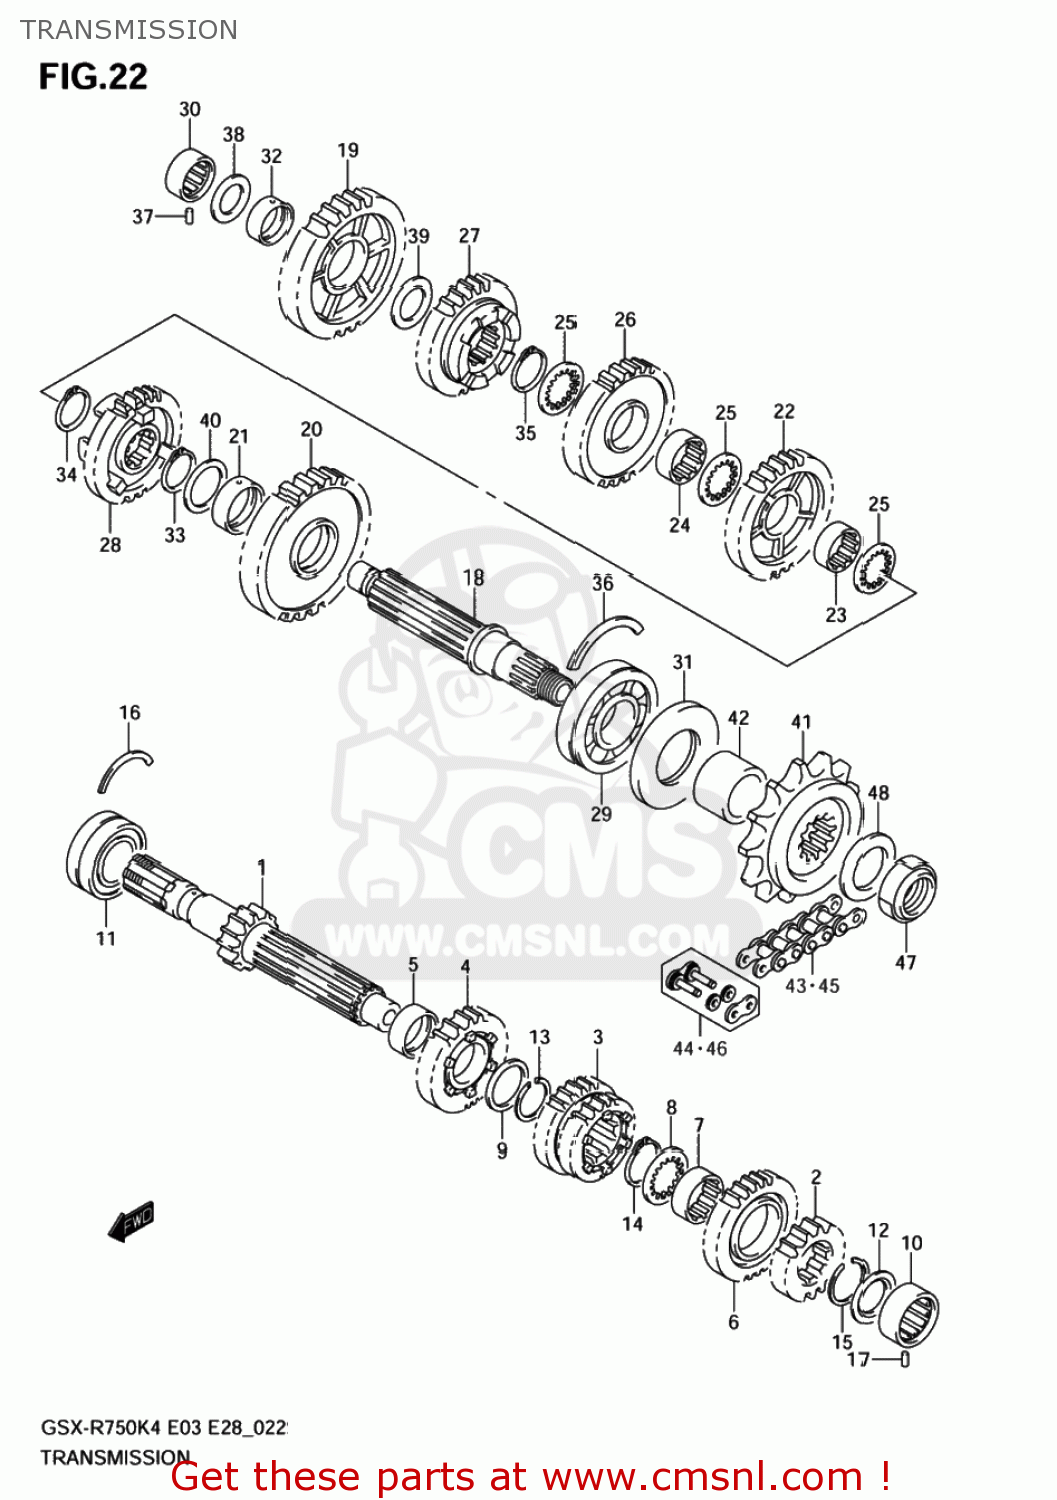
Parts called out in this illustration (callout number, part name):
1	SHAFT,COUNTER
2	GEAR,2ND DRIVE
3	GEAR,THIRD & FOURTH DRIVE
4	GEAR,5TH DRIVE
5	BUSH,5TH DRIVE GEAR
6	GEAR,6TH DRIVE
7	BUSH,6TH DRIVE GEAR
8	WASHER,LOCK
9	SHIM(27X36X2.5)
10	BEARING(20X34X13.5)
11	BEARING(25X52X20.6)
12	SEAL,OIL(20X31.2X2.7)
13	CIRCLIP
14	CIRCLIP
15	CIRCLIP
16	C RING
17	PIN(6X10)
18	SHAFT,DRIVE
19	GEAR,1ST DRIVE
20	GEAR,2ND DRIVE
21	BUSH,2ND DRIVEN GEAR
22	GEAR,3RD DRIVEN(NT:37)
23	BUSH,3RD DRIVEN GEAR
24	BUSH,3RD DRIVEN GEAR
25	WASHER,3RD & 4TH DRIVEN
26	GEAR,4TH DRIVEN(NT:29)
27	GEAR,5TH DRIVEN
28	GEAR,6TH DRIVEN
29	BEARING(28X70X18)
30	BEARING(20X34X13.5)
31	SEAL,OIL(34.8X70X6)
32	BUSH(22X26X9)
33	CIRCLIP
34	CIRCLIP
35	CIRCLIP
36	C RING
37	PIN(6X10)
38	SHIM(20X34X1)
39	SHIM(22X34X1)
40	WASHER(27X36X1)
41	SPROCKET,ENGINE(17T)
42	SPACER,ENGINE SPROCKET
43	CHAIN,DRIVE
44	JOINT SET,DRIVE CHAIN
45	CHAIN,DRIVE
46	JOINT SET,DRIVE CHAIN
47	NUT
48	WASHER(25X41X3)
